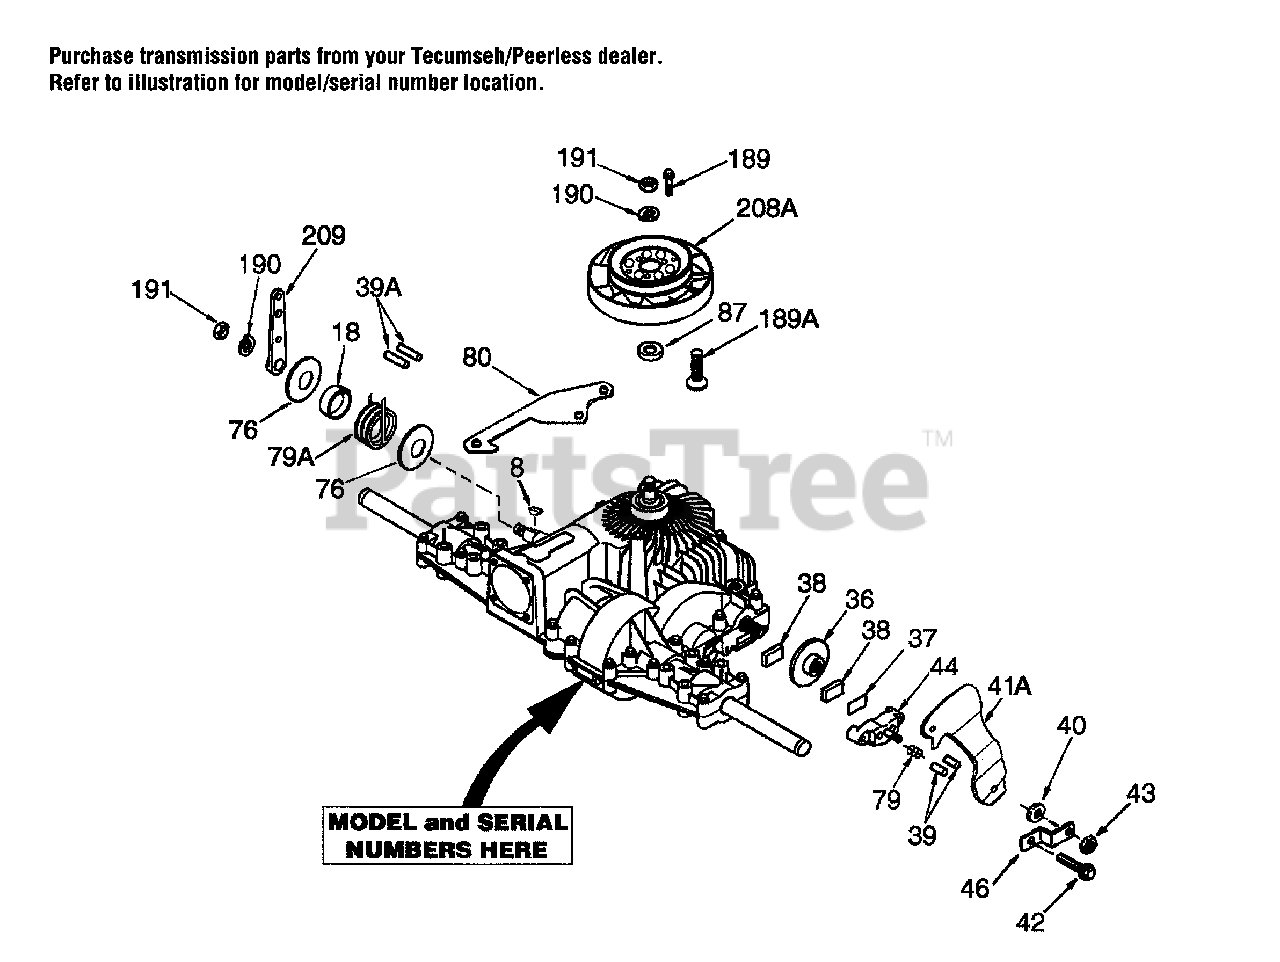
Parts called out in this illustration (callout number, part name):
8	Woodruff Key
36	Brake Disk
37	Brake Pad Plate
38	Brake Pad (pkg of 2)
39	Dowel Pin
39A	Dowel Pin
40	Flat Washer
41A	Brake Lever
42	Screw 1/4-20 x 1-1/4
43	Locknut 5/16-24
44	Brake Pad Holder
46	Brake Lever Bracket
76	Flat Washer
79A	Neutral Return Spring
80	Control Lever Stop
87	Oil Seal 5/8
189	Drive Screw #6 x 1/2
189A	Screw 10-24 x 1/2
190	Lock washer
191	Nut 7/16-20
208A	Fan/Coupling Assy 2WS
209	Control lever
